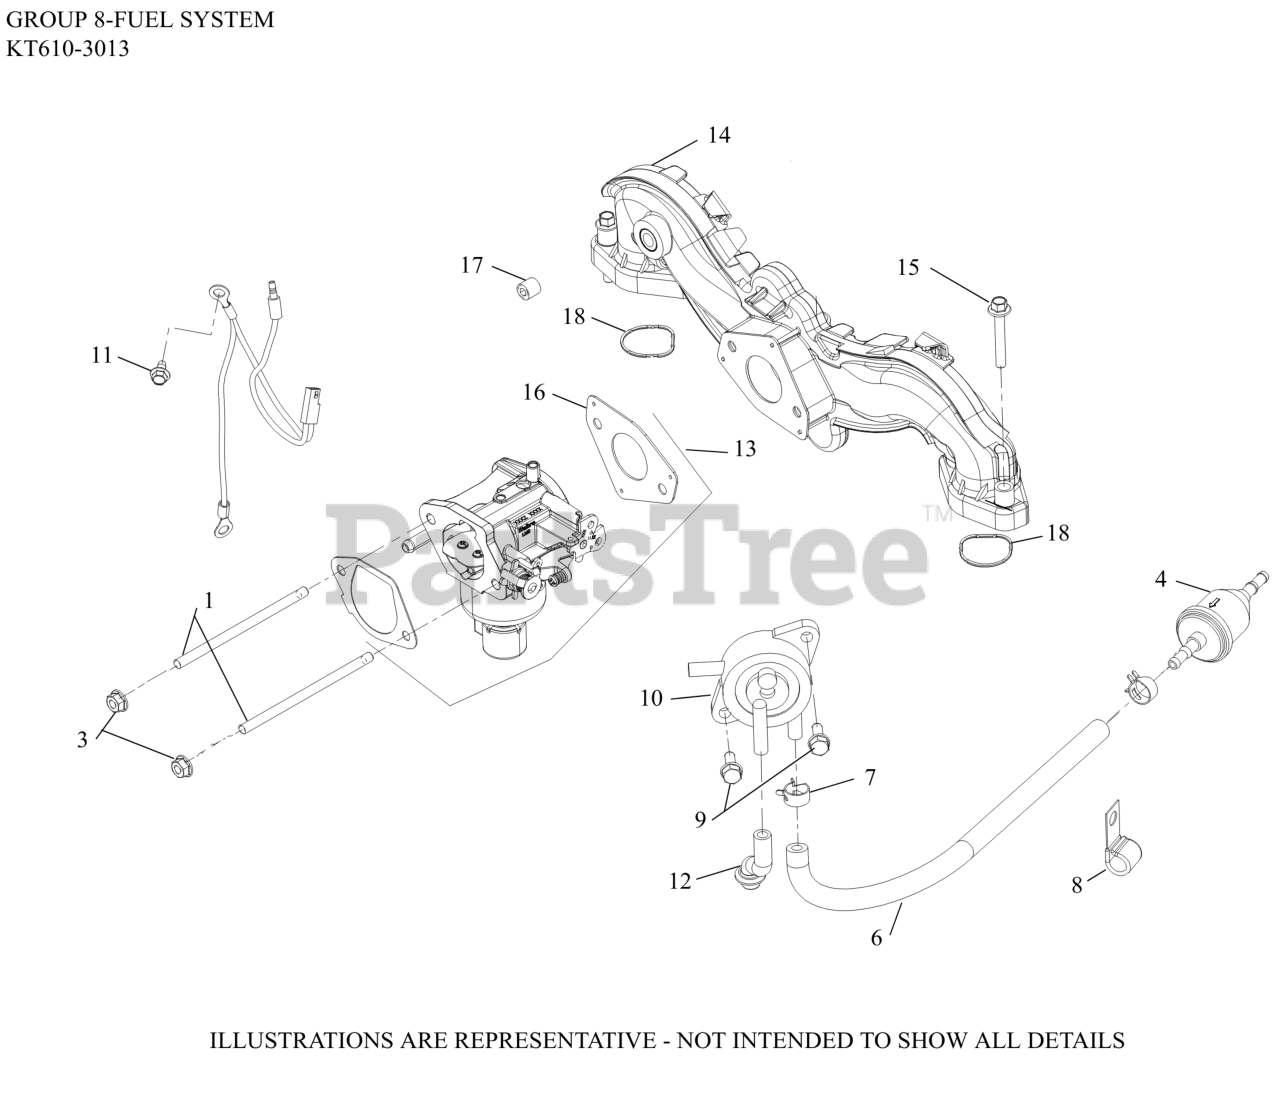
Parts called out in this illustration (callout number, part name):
3	NUT, FLG M6X1.0
4	FILTER,FUEL 51 MICRON (FUEL PUMP)
6	HOSE,LW PERM.FUEL 24.00"-USE 25 111 81-S
7	SPRING CLAMP, HOSE
8	CLIP, CABLE
9	SCREW, TAP M6X1.7X18
10	PUMP, FUEL (PULSE)-(#2539326S)
11	SCREW, THREAD FORMING
12	HOSE, PULSE PUMP(STEEL COVERS)
13	KIT,CARB(WALBRO)
14	KIT, INTAKE MANIFOLD-(#24164277S)
15	SCREW, FLG M6X1.0X40
16	GASKET, CARBURETOR
17	PLUG, CTSK PIPE 1/8"
18	O-RING, INTAKE PORT (PIM)
NI	KIT,REPAIR OVERHAUL(WALBRO)
NI	KIT,BOWL O-RING(WALBRO)
NI	KIT, HI ALTITUDE (5000 FT) 19MM
NI	KIT,SOLENOID REPAIR(WALBRO)
NI	KIT,REPAIR FLOAT(WALBRO)
